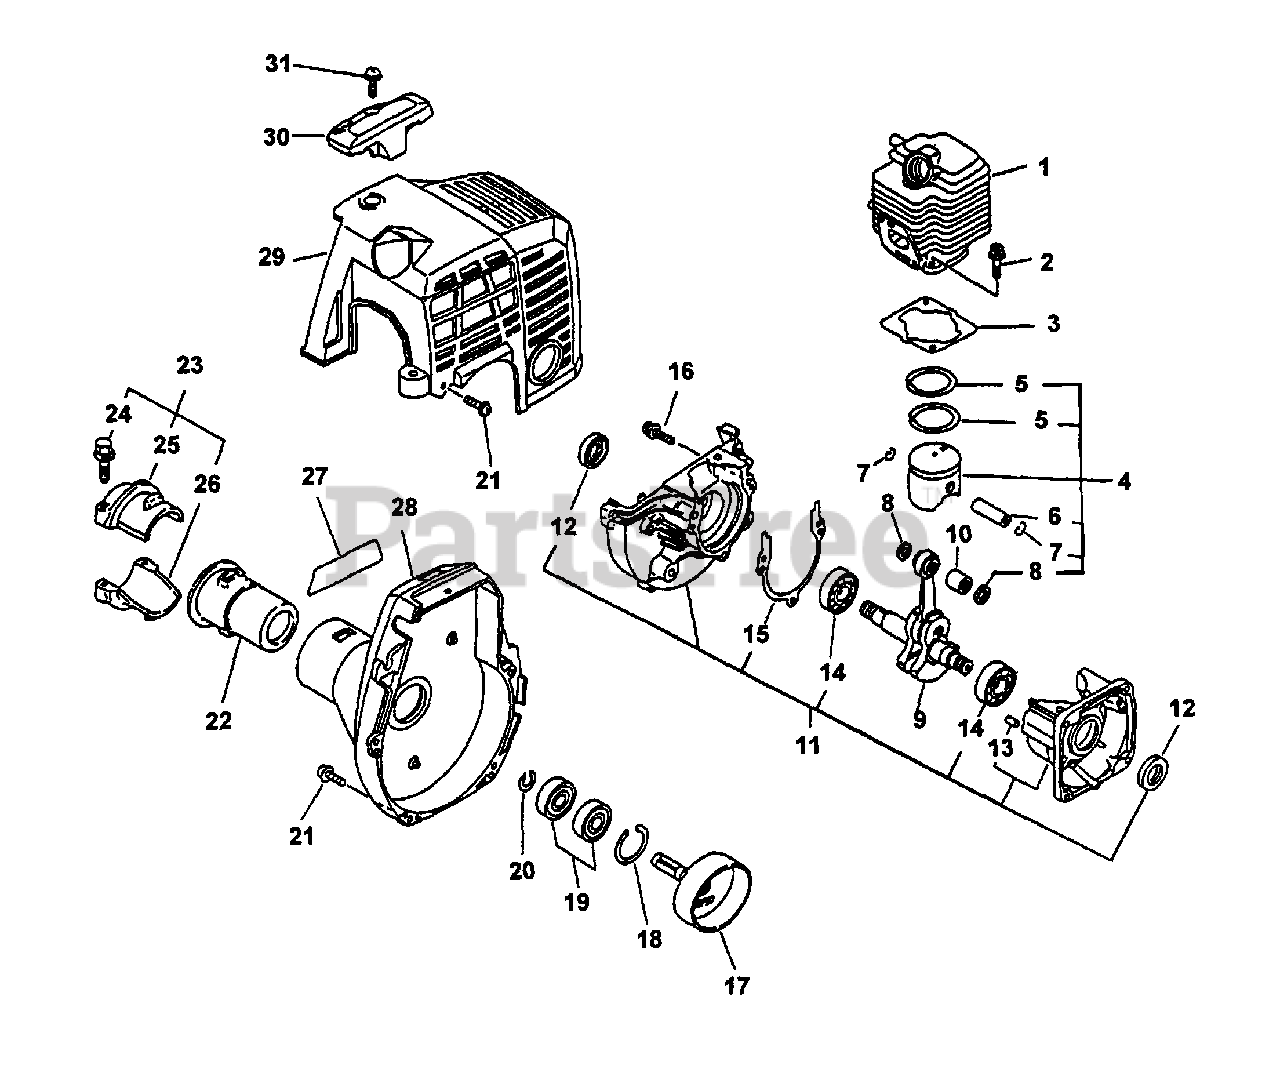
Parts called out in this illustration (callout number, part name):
1	CYLINDER
2	BOLT 5×22
3	GASKET, CYLINDER
4	PISTON KIT
5	RING, PISTON
6	PIN, PISTON 8
7	RING, SNAP
8	WASHER, THRUST
9	CRANKSHAFT ASSY
10	BEARING, NEEDLE
11	CRANKCASE KIT
12	SEAL, OIL 12
13	PIN, LOCATING 4
14	BEARING, BALL - 6201 C3
15	GASKET, CRANKCASE
16	BOLT 5×28
17	DRUM, CLUTCH
18	RING, SNAP 28
19	BEARING, BALL 6001
20	RING, RETAINING - 12
21	BOLT 4×16
22	CUSHION Ø25
23	RETAINER KIT
24	BOLT - 5×25
25	HOLDER, MAIN PIPE - UPPER
26	HOLDER - LOWER
27	LABEL - MODEL
28	COVER ASSY, FAN
29	COVER, ENGINE
30	GUARD, TOP
31	SCREW 5×16
